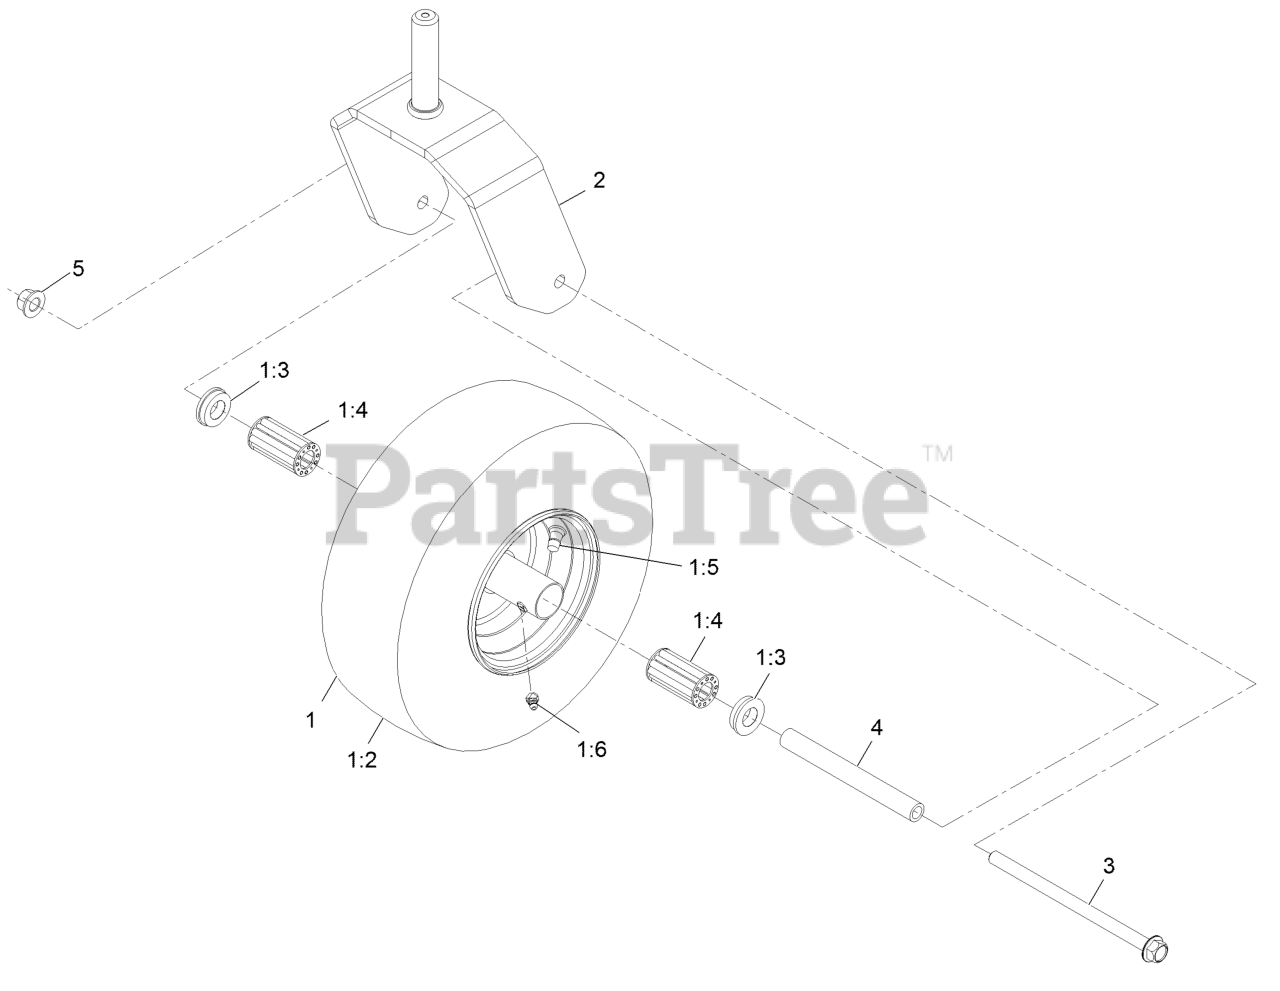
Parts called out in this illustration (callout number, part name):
1	ASM-WHEEL AND TIRE 13X6.5
1:2	TIRE
1:3	BUSHING-FLANGE
1:4	BEARING
1:5	VALVE
1:6	FITTING-ZERK
2	FORK-CASTER
3	SCREW-HHF
4	SPANNER-WHEEL, CASTER
5	Nut-Lock 1/2-13
